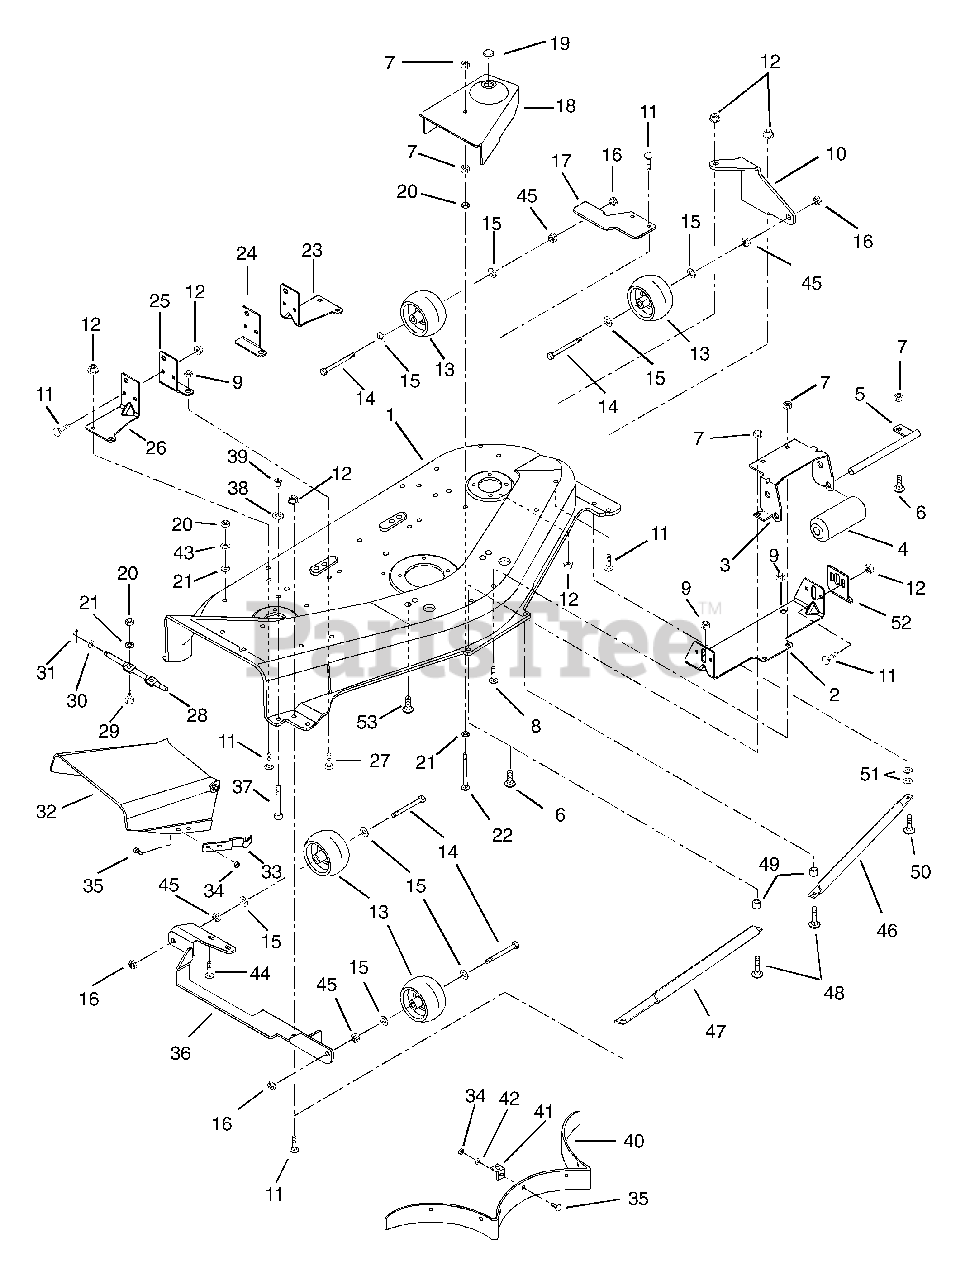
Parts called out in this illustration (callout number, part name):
1	MOWER PAN W/DECALS 48"- ORANGE
2	FRONT HANGER
3	BRACKET, ROLLER
5	ROLLER SHAFT
6	@BLT-RDHDSQNK .31-18X.75 G5YZ
7	@NUT-LK-CTR .31-18 YWZC
8	@BLT-RHDSSQNK .31-18X.62 G5YZ
9	@NUT-LK-CTR .50-13 YWZC
10	BRACKET, LEFT FRONT
11	BLT-RDHDSQSHK.31-18X.75 GR2 YW
12	@NUT-SPNLK-FLG .312-18 YWZC
13	WHEEL 5 X 3
14	@BLT-HEX .50-13X4.50 GR5 YWZC
15	WSHR-FL-NYL .518X1.000X.080
16	@NUT-LK-CTR .50-13 YWZC
17	BRACKET, LEFT REAR
18	COVER, RIGHT HAND
18	COVER, LEFT HAND
19	BUTTON PLUG 1.0
20	@NUT-HEX .31-18 YWZC
21	WSHR-LK .312X.097 HVY YWZC
22	BLT-RDHDSQNK .31-18X3.25 SHTPL
23	LH REAR HANGER - ORANGE
24	LH REAR HANGER SUPPORT
25	RH REAR HANGER SUPPORT
26	RH REAR HANGER - ORANGE
27	@BLT-HEX .50-13X1.00 GR5 YWZC
28	HINGE PIN
29	@BLT-HEX .31-18X.75 GR5 YWZC
30	@WSHR-FL-STL.406X.812X.065 YWZ
31	@PIN-CTR .09X.75 EXTPRSQCT YWZ
32	CHUTE EXTENSION
33	FLAT SPRING - ORANGE
34	@NUT-LK-CTR .25-20 YWZC
35	BLT-RDHDSQSHNK.25-20X.50 YWZC
36	MOUNT ROLLER
37	@BLT-HEX .38-16X2.50 GR5 YWZC
38	WSHR-LK .375X.115 HVY YWZC
39	@NUT-HEX .38-16 YWZC
40	BAFFLE
41	TAB, MTG.
42	@WSHR-FL-STL.281X.62X.065 YWZC
43	@WSHR-FL-STL.312X.734X.065 YWZ
44	@BLT-RDHDSQNK .31-18X1.00 G5YZ
45	@NUT-LK-CTR .50-13 YWZC
46	GUARD - FOOT - LEFT - ORANGE
47	GUARD - FOOR - RIGHT - ORANGE
48	@BLT-RDHDSQNK .31-18X1.50 G5YZ
49	SPACER .375 X .625 X .500
50	@BLT-RDHDSQNK .31-18X1.25 G5YZ
51	WSHR-FL-STL .390X.75X.125 YWZC
52	MOWER ADJUSTMENT TAB
53	@BLT-RDHDSQNK .50-13X1.00 G2YW
